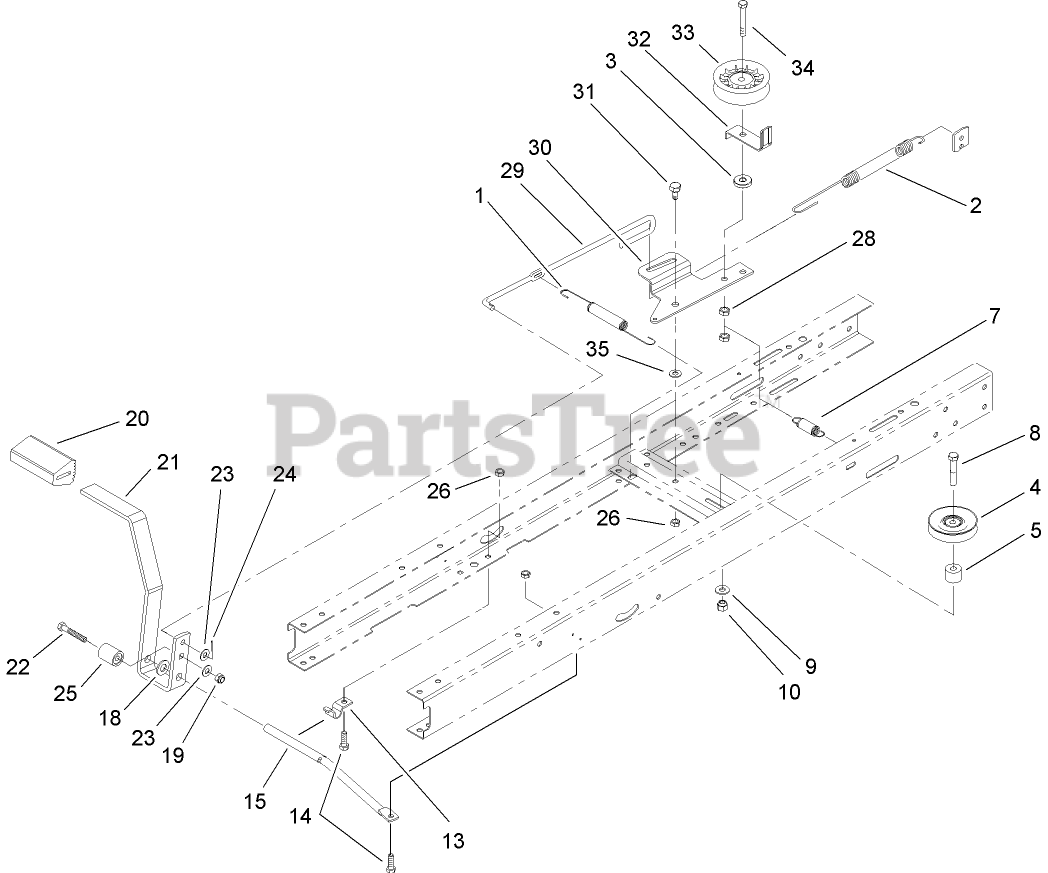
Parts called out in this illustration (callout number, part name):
1	SPRING-EXTENSION
2	SPRING-EXTENSION
3	WASHER
4	PULLEY-IDLER
5	SPACER
7	SPRING-EXTENSION
8	SCREW-HH
9	WASHER-FLAT
10	NUT-LOCK, NI
13	CLAMP-PIVOT, SHIFT
14	SCREW-HH
15	ROD-PIVOT, PEDAL
18	WASHER-FLAT
19	NUT-LOCK, NI
20	PAD-PEDAL
21	PEDAL-CLUTCH/BRAKE, HYDRO
22	SCREW-HH
23	WASHER-PLAIN
24	PIN-COTTER
25	SPACER
26	NUT-LOCK, NI
29	ROD-CLUTCH/BRAKE
30	ARM-IDLER
31	BOLT-SHOULDER
32	GUIDE-IDLER, BELT
33	PULLEY-IDLER
34	SCREW-HH
35	WASHER-PIVOT
